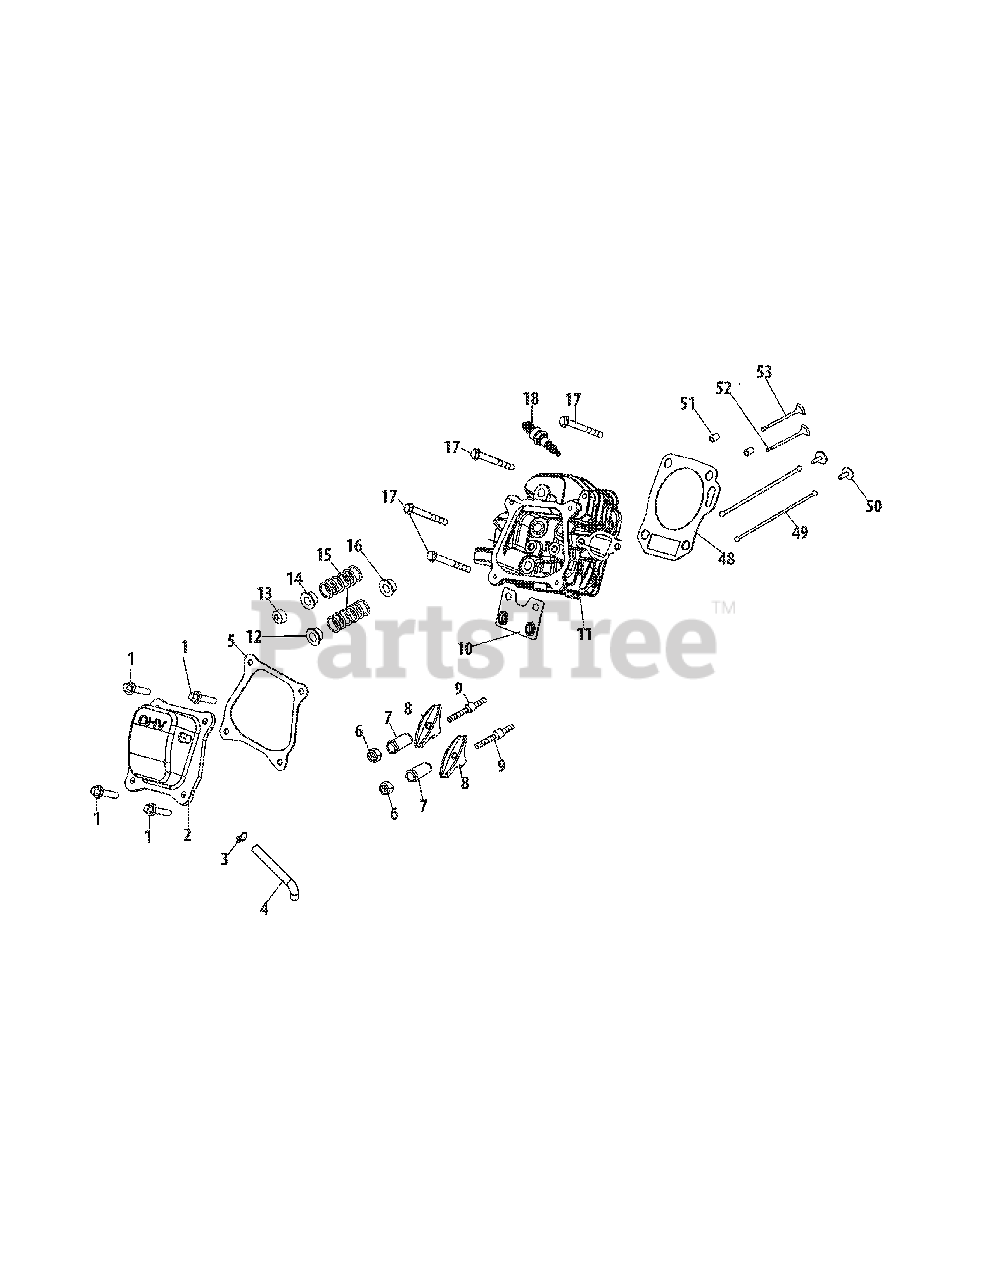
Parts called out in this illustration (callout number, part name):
1	Bolt, M6×16
2	Valve Cover
4	Breather Hose
5	Gasket, Valve Cover
6	Lock Nut
7	Adjust Nut
8	Rocker Arm
10	Rocker Arm Base
11	Cylinder Head
12	Valve Spring Seat
13	Valve Adjust Cap, Exhaust
14	Valve Spring Seat
15	Valve Spring
16	Intake Valve Seal
17	Bolt, M8×55
18	Spark Plug
48	Gasket, Cylinder Head
49	Push Rod
50	Tappet
51	Pin, 10×16
52	Intake Vavle
53	Exhaust Valve
